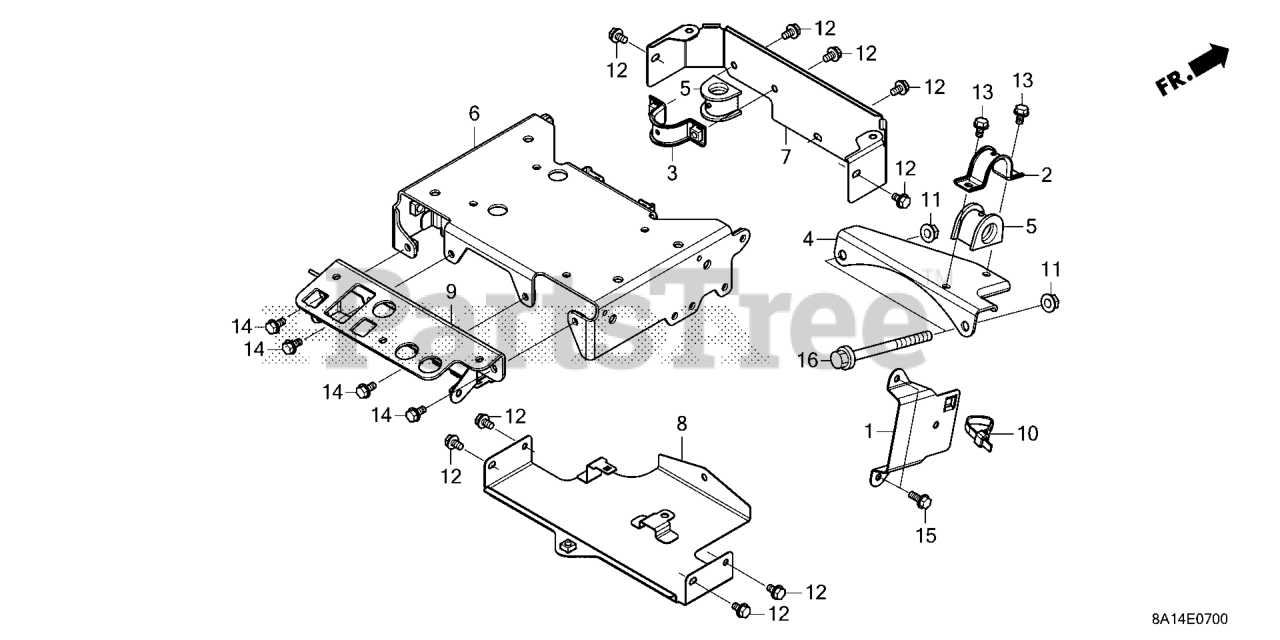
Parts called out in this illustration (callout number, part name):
1	STAY, MOTOR HARNESS
4	STAY, MOTOR BRACKET
5	GROMMET, HARNESS
7	FRAME, FR.
8	FRAME (LOWER)
9	BASE, CONTROL
10	BAND, HARNESS
11	NUT, FLANGE (8MM)
12	BOLT, FLANGE (6X10)
13	BOLT, FLANGE (6X10)
14	BOLT, FLANGE (6X12) Use from Engine SN 2086984.
15	BOLT, FLANGE (6X14)
16	BOLT, FLANGE (8X125)
